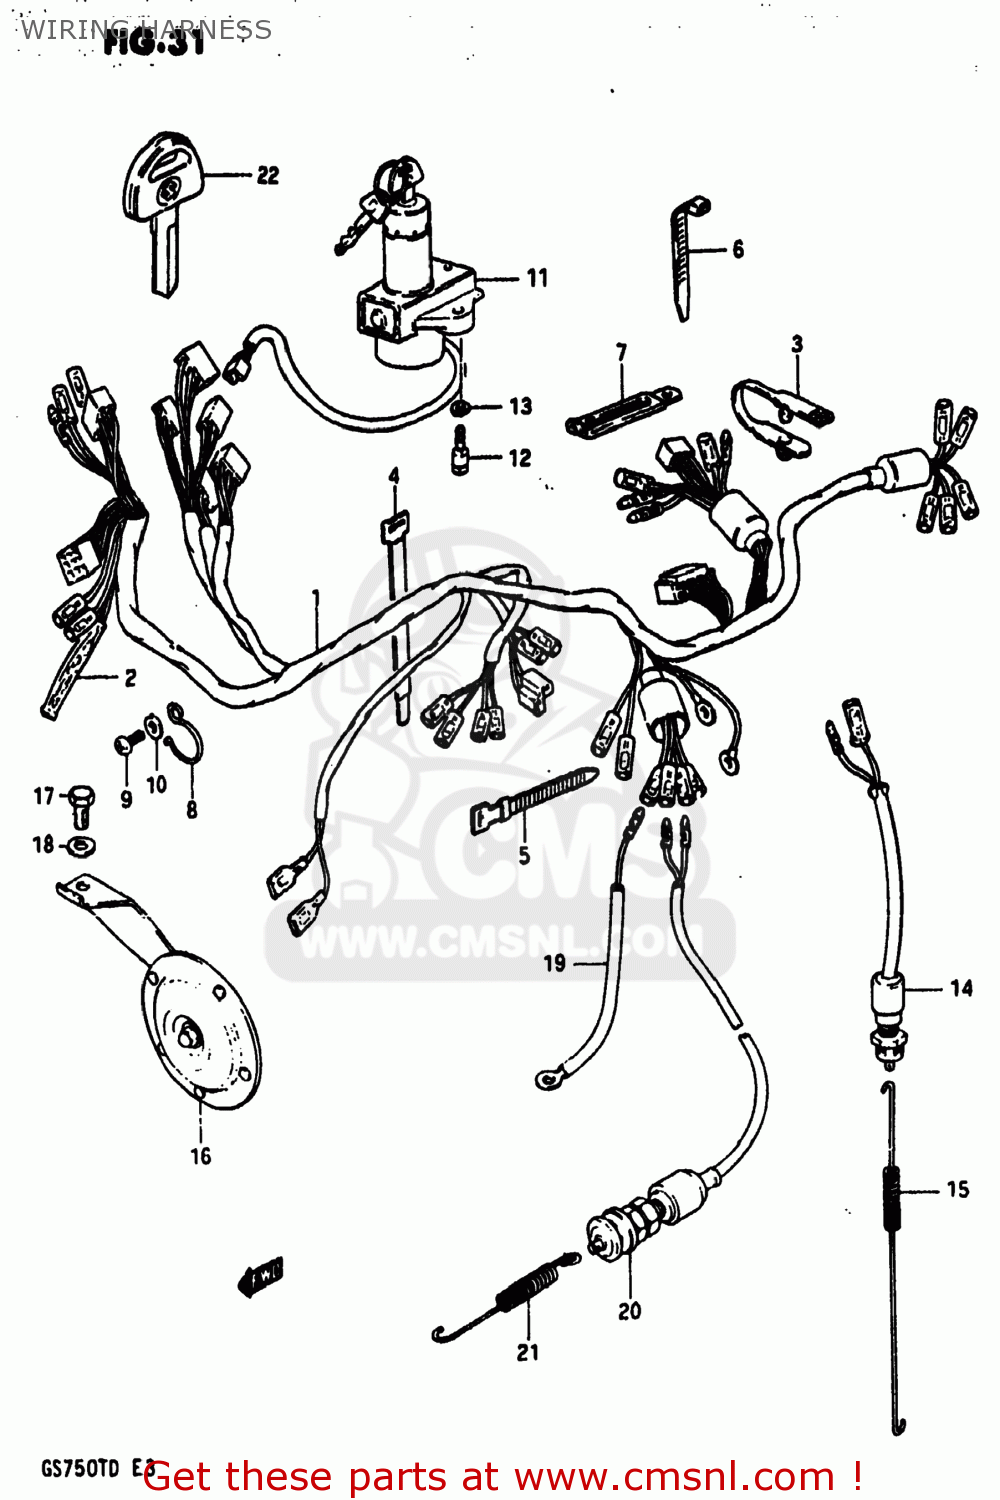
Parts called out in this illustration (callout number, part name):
1	HARNESS,WIRING
2	DIODE
3	CLAMP,L:88
4	CLAMP
5	CLAMP(L:120)
6	CLAMP(L:125)
7	CLAMP
8	GUIDE,WIRING HARNESS
9	SCREW 6X12
10	WASHER
11	SWITCH ASSY,IGNITION
12	BOLT
13	LOCK WASHER
14	SWITCH ASSEMBLY,BRAKE LAMP
15	SPRING
16	HORN ASSEMBLY
17	BOLT 8X12
18	WASHER
19	WIRE
20	SWITCH ASSEMBLY,SIDE STAND
21	SPRING
22	KEY,BLANK
